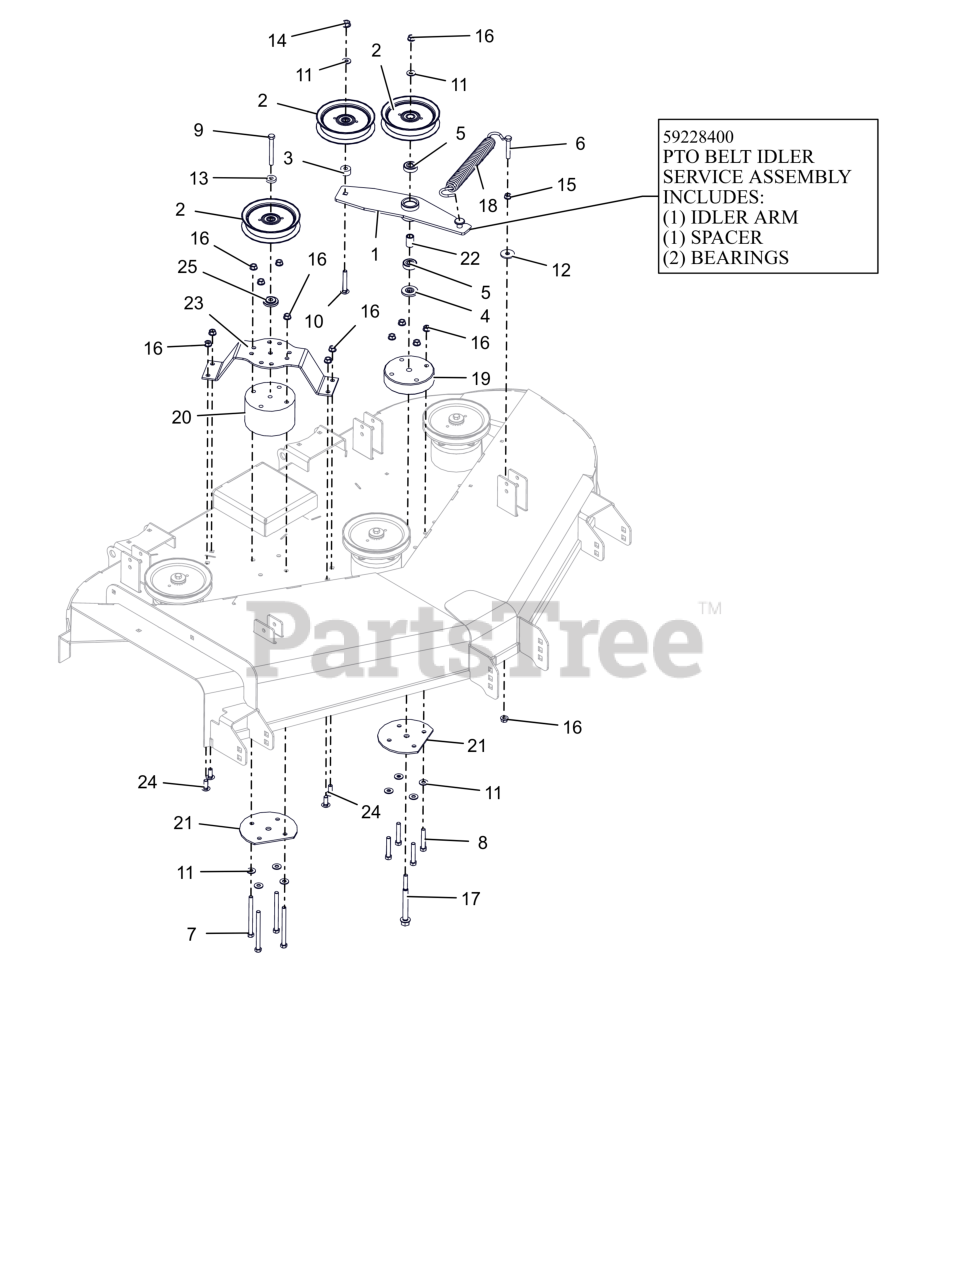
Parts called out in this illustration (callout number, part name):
1	WLDMT, IDLER ARM
1	PTO, IDLER ARM, ASSY
2	IDLER, FLAT 5.00"
3	SPACER .390X1.000X.562
4	SPACER, IDLER ARM
5	BRG-BALL .500X1.38X.437
6	BLT,HEX .38-16X2.25 G5 ZCC
7	BLT, HEX 0.375-16X4.5 GR8 ZCC
8	BLT, HEX 0.375-16X2.25 GR8 ZCC
9	BLT, HEX 0.375-16X3.25 GR8 ZCC
10	BLT,RHSN .38-16X2.50 G5 ZCC
11	WSHR,FLT .375X.875X.083 ZCC
12	WSHR,FLT .406X1.375X.135 ZCC
13	WSHR, FLT .390X1.00X.250 ZCC
15	NUT, SPNLK-FLG .38-16 G5 ZCC
16	NUT-LK-CTR-FLG .375-16 GF ZCC
17	BLT-SHLDR .500 X 3.66 X .38-16
18	SPRING, EXTENSION
19	PEDESTAL, IDLER STAND OFF
20	PEDESTAL, IDLER STAND OFF
21	PLATE, REINFORCING
22	SPACER .510 X .75 X 1.1485
23	BRACE, IDLER SUPPORT
24	BLT,RHSSN .38-16X1.00 G5 ZCC
25	RETAINER, SHEAVE
